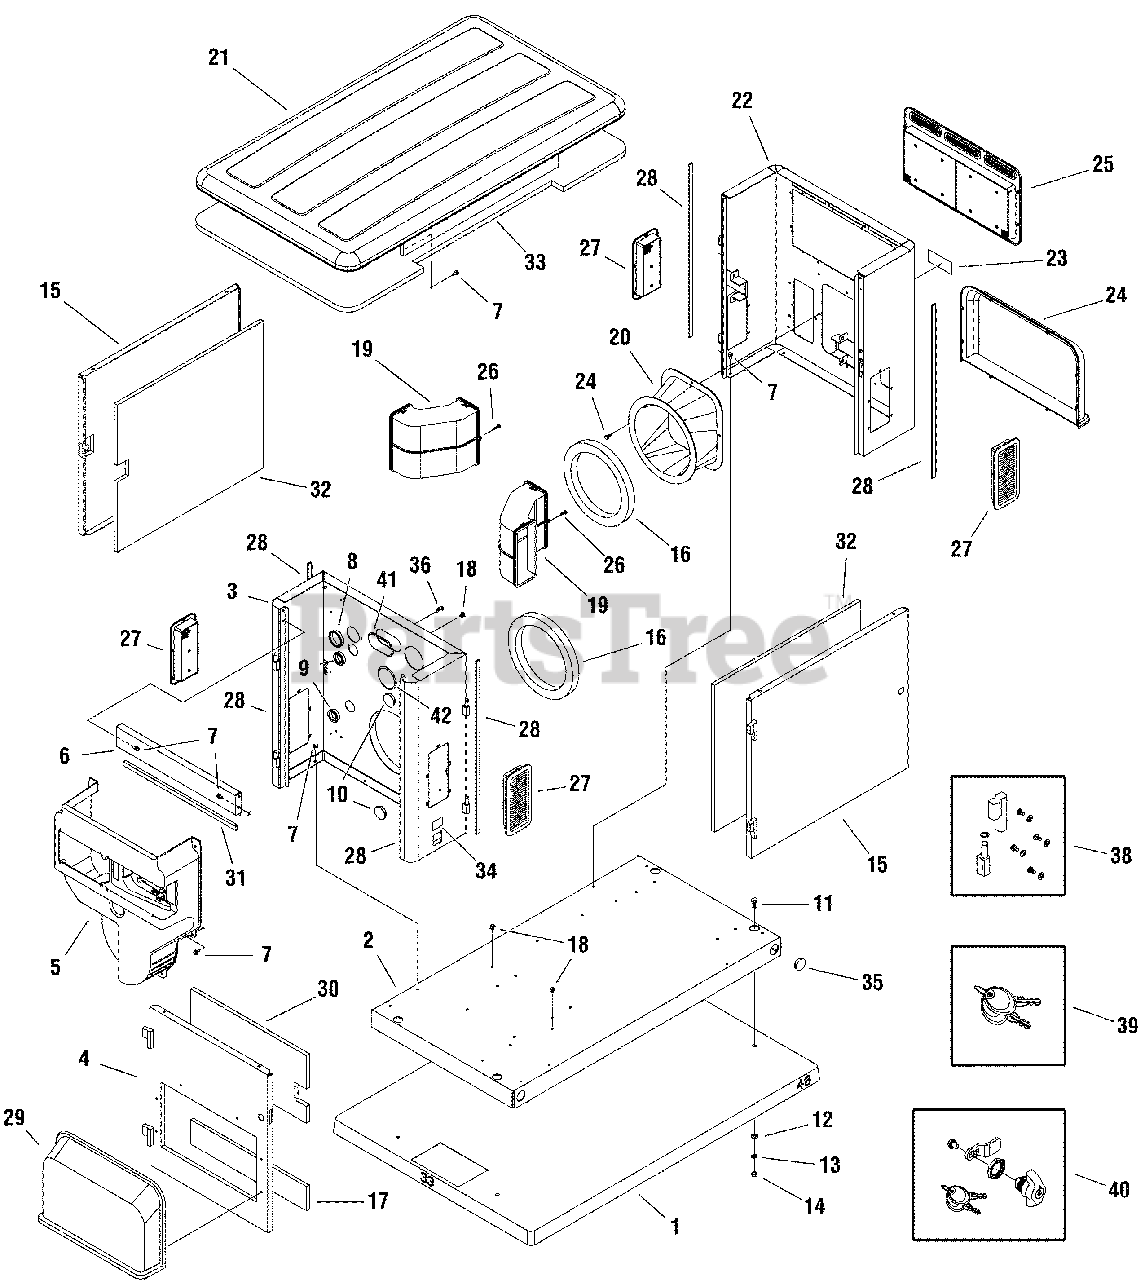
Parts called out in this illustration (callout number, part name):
3	BULKHEAD, Engine
4	DOOR
5	DUCT
6	SUPPORT, Rail
7	BOLT
10	REGULATOR-VOLTAGE
11	* CAP SCREW, Hex Head-3/8 - 16 x 1
11	* HHCS-3/8 - 16 x 1
12	* WASHER, Flat 3/8-M10
12	* WASHER-FLAT 3/8-M10
13	* WASHER, Lock 3/8
13	* WASHER-LOCK 3/8
14	* NUT, 3/8-16
14	* NUT-3/8-16
15	DOOR
18	MOUNT, Tie wrap
20	ADAPTER, Alternator
20	SEAL, Foam
21	ROOF
22	BULKHEAD, Alternator
24	COVER, Air Intake
29	COVER, Air Intake
34	DECAL
38	DECAL
